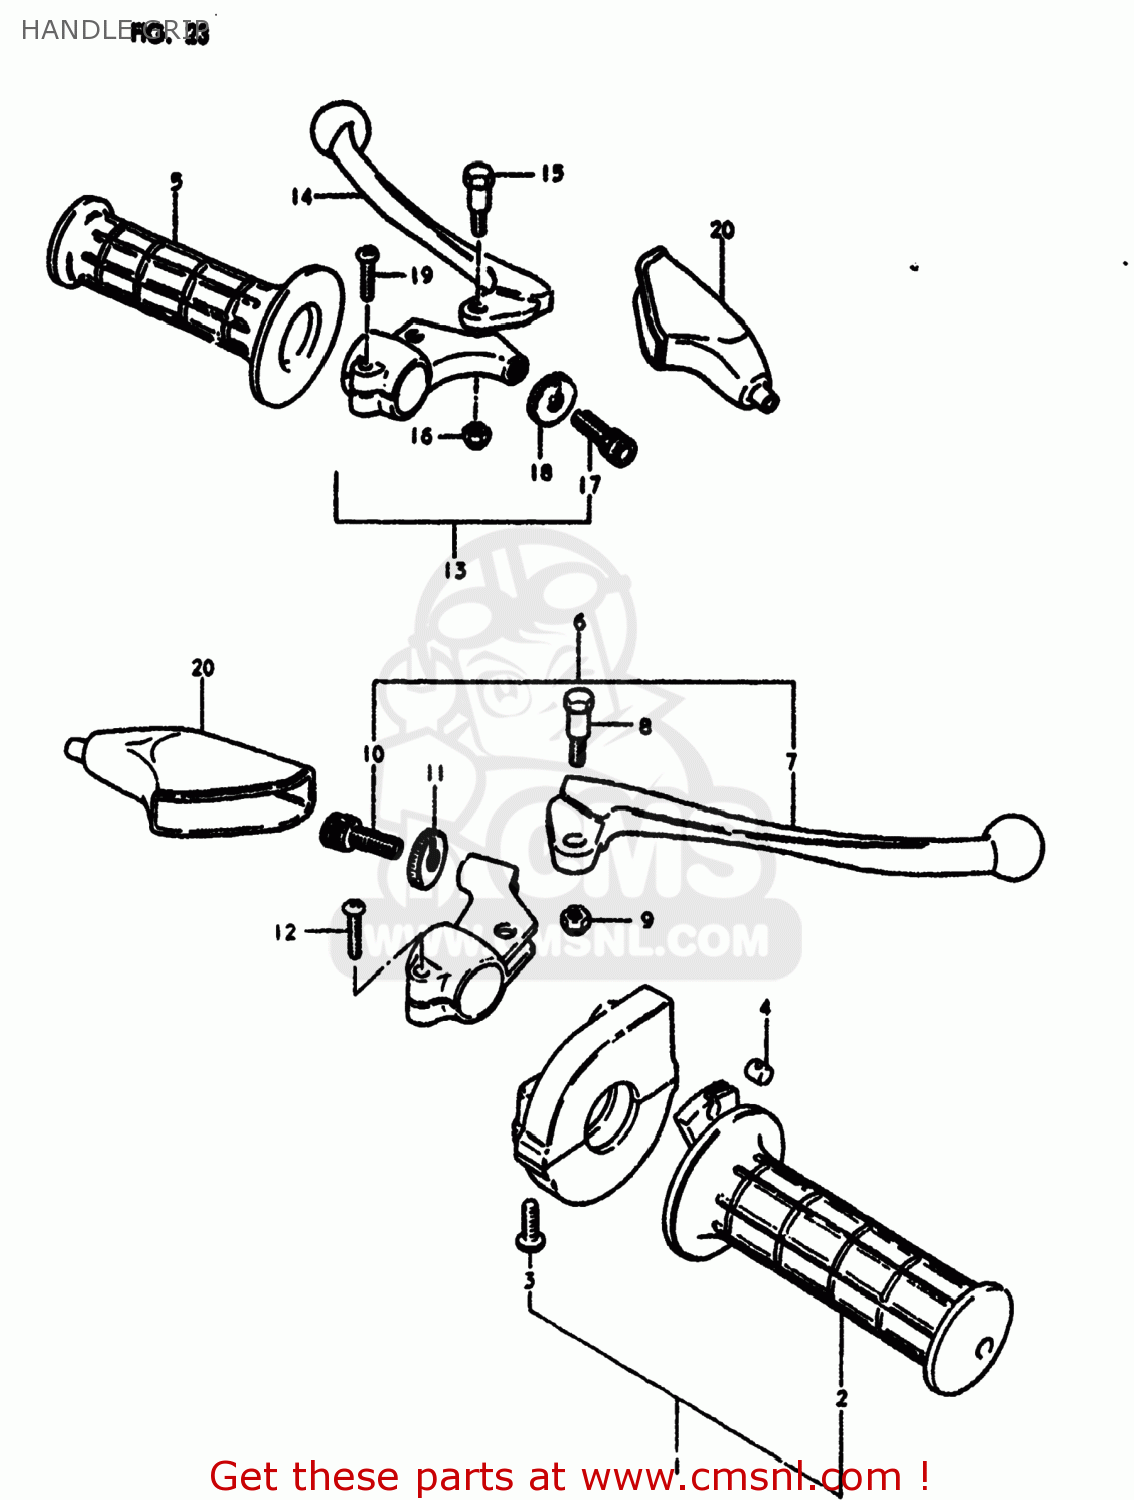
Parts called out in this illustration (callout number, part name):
1	CASE ASSEMBLY,THROTTLE
2	GRIP,THROTTLE
3	SCREW
4	PIECE,THROTTLE END
5	GRIP,LEFT
6	LEVER ASSY,BRAKE
7	LEVER,BRAKE
8	BOLT,LEVER
9	NUT 6MM
10	ADJUSTER,CABLE
11	NUT,CABLE ADJUSTER
12	SCREW
13	LEVER ASSY,CLUTCH
14	LEVER,CLUTCH
15	BOLT,LEVER
16	NUT 6MM
17	ADJUSTER,CABLE
18	NUT,CABLE ADJUSTER
19	SCREW
20	COVER,CLUTCH LEVER
